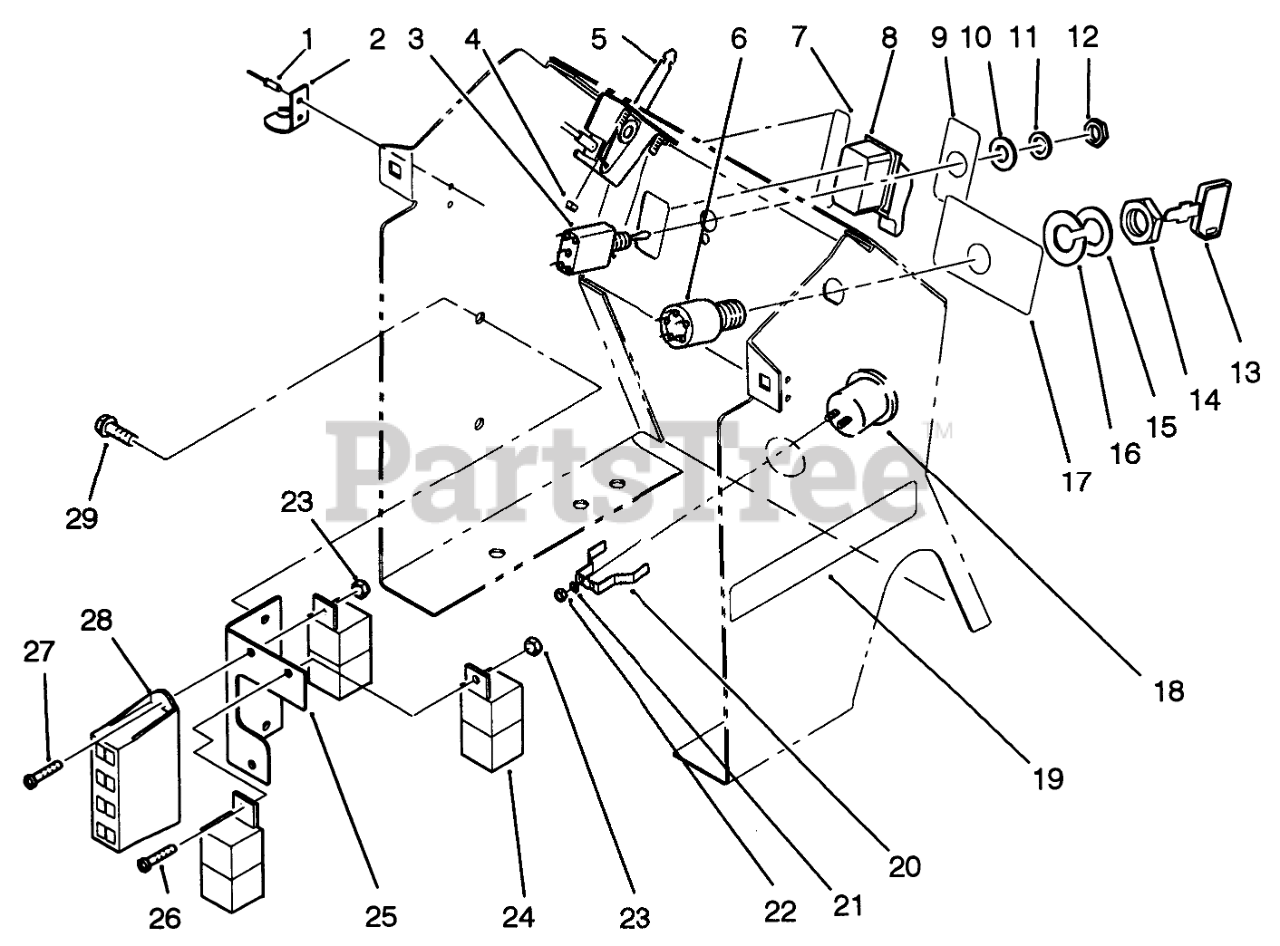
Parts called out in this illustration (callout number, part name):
1	POPRIVET 1/8X 1/8 BK
2	KEEPER-LATCH
3	Switch-Lights (Incl. Ref. #10-14)
5	CONTROL-THROTTLE
6	Switch-Ignition, Assembly (Incl. Ref #13, 14 & 16)
7	DECAL-PTO
8	PTO-SWITCH W/COVER
9	DECAL-LIGHTS
10	TAB-WASHER
11	Washer
13	Key
15	Washer
16	LOCKWASHER
17	DECAL-IGNITION
18	HOUR-METER
19	DECAL-MODEL HYDRO
20	CLAMP-HOUR METER
21	WASHER-LOCK
22	Nut
23	Nut
24	RELAY
25	BRKT-FUSE HOLDER B
26	SCREW-PPH
27	SCREW
28	FUSE-HOLDER 4 WAY
29	TRS-1/4-20X1/2 BLACK
